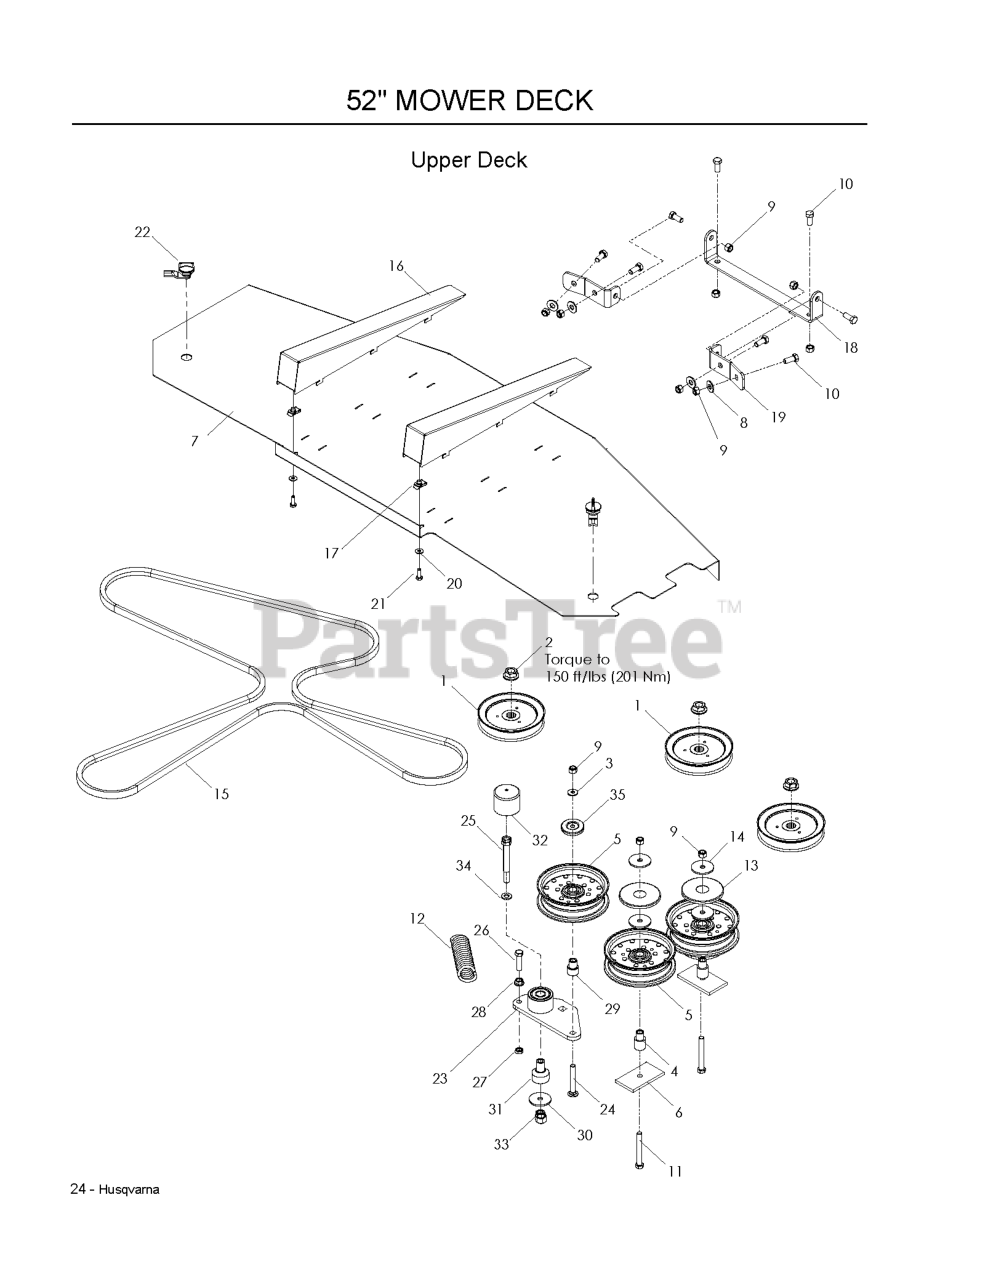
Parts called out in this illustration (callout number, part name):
1	PULLEY - 6.57
2	NUT FLANGE 3/4-16
3	WASHER, 3/8 THICK
4	IDLER BUSHING
5	IDLER PULLEY
6	SUPPORT PLATE
7	COVER - BELT, 52 PAINTED
8	WASHER 3/8 FLAT
9	NUT 3/8-16 NYLOC
10	HCS 3/8-16 X 7/8 GR 5 ZD
11	HCS 3/8C X 3
13	TOP DUST CAP
14	WASHER, 3/8 SPEC
15	V-BELT 142
16	WEDGE - PAINTED
17	1/4C - U TYPE RETAINER
18	HINGE, BIN
19	BASE HINGE - PAINTED
20	WASHER 1/4 SAE
21	HCS 1/4C X 3/4 HCS
22	LATCH, SHORT WING
23	ARM-IDLER W/BRG
24	RHSNB 3/8-16 X 2.75
25	HCS 1/2C X 3 1/4
26	HCS 3/8-16 X 1-1/2
27	NUT 3/8-16 HEX JAM
28	NUT 3/8C WHIZ
29	BUSHING, IDLER
30	WASHER, SUPPORT
31	PIVOT, BEARING
32	CAP, VINYL
33	NUT 1/2-13 HEX NYLOC ZD
34	CONTACT BELLSPR 1/2
35	DUST SHIELD
